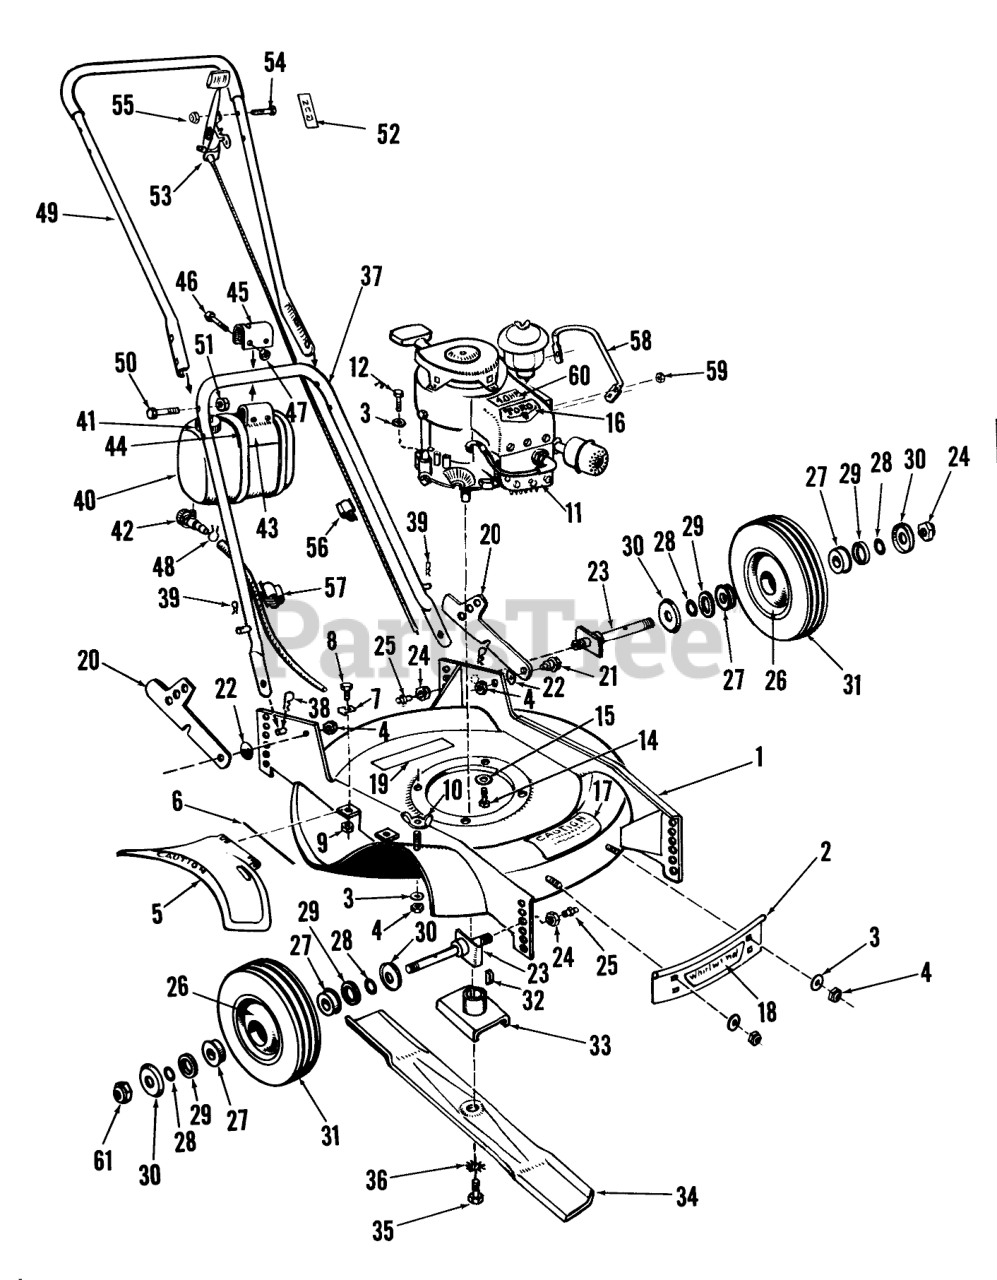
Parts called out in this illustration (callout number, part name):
1	Housing
2	Guard
3	WASHER-PLAIN
4	Nut
5	Deflector
6	HINGE PIN
7	Clamp
8	SCREW-HH
9	Nut
10	Wing Nut
11	Engine
12	SCREW-HH
14	SCREW-HH
15	WASHER-LOCK
16	Decal
17	Decal
18	Decal
19	Decal
20	Latch
21	SCREW-SHOULDER
22	WASHER-SPRING
23	Spindle Assembly (Incl. Ref. No.25)
24	NUT-LOCK, NI
25	FITTING-GREASE
26	Wheel Assy. (Incl. (2) Ref. No.27 Bearings)
27	BEARING-BALL
28	O-RING
29	Washer
30	SLINGER
31	1.75-8 SEMIPNEU TIRE
32	KEY-WOODRUFF
33	BLADE RETAINER WA
34	Blade
35	SPECIAL SCREW
36	WASHER-LOCK
37	Lower Handle
38	PIN-COTTER, HAIR
39	PIN-COTTER
40	Tank
42	.125 ID SHUTOFF VALVE
43	FUEL TANK BRACKET
44	TANK STRAP
45	Clamp, Fuel Tank
46	SCREW-HH
47	Nut
48	Clamp
49	Upper Handle Assy.
50	SCREW-HH
51	NUT-KEPS
52	Decal
53	Throttle Control
54	10-24X1-1/8 RND HD MS
55	NUT-LOCK, NI
56	Clamp
57	CLAMP
59	NUT-LOCK NI
60	Decal
61	Nut
